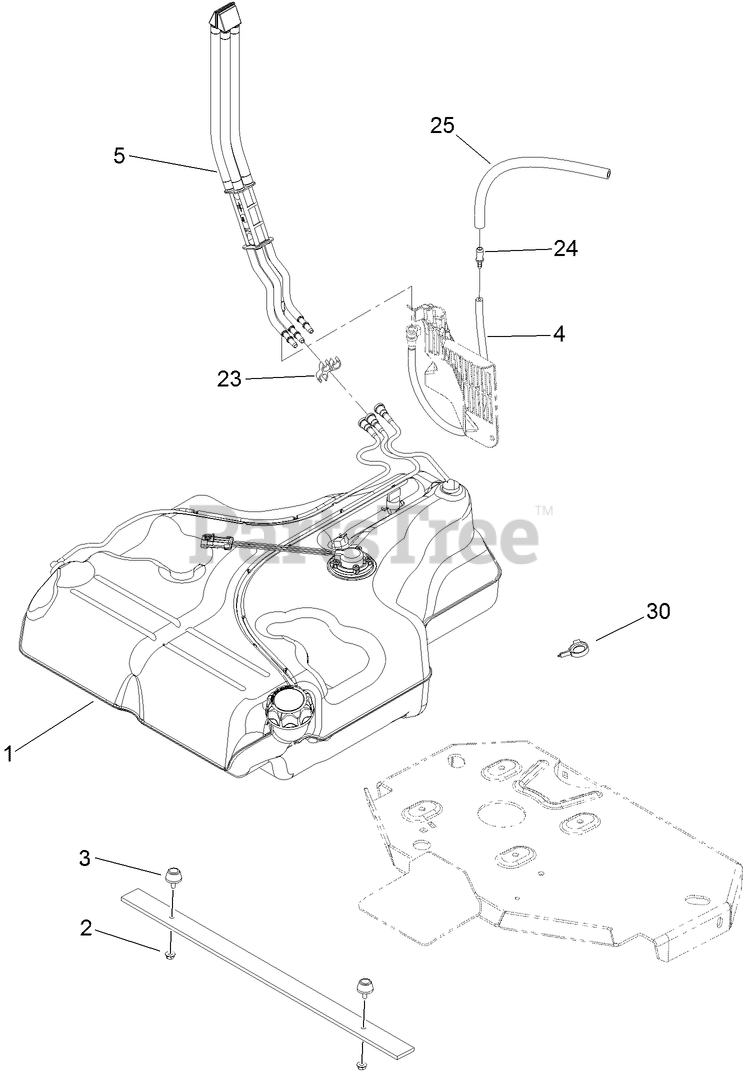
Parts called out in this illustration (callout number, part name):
1	FUEL TANK ASM
2	NUT-HF
3	BUMPER-RUBBER
4	HOSE ASM
5	FUEL MANIFOLD VENT ASM
23	CLIP-SPACER
24	FITTING-STRAIGHT
25	HOSE-FUEL
30	CLAMP-HOSE
